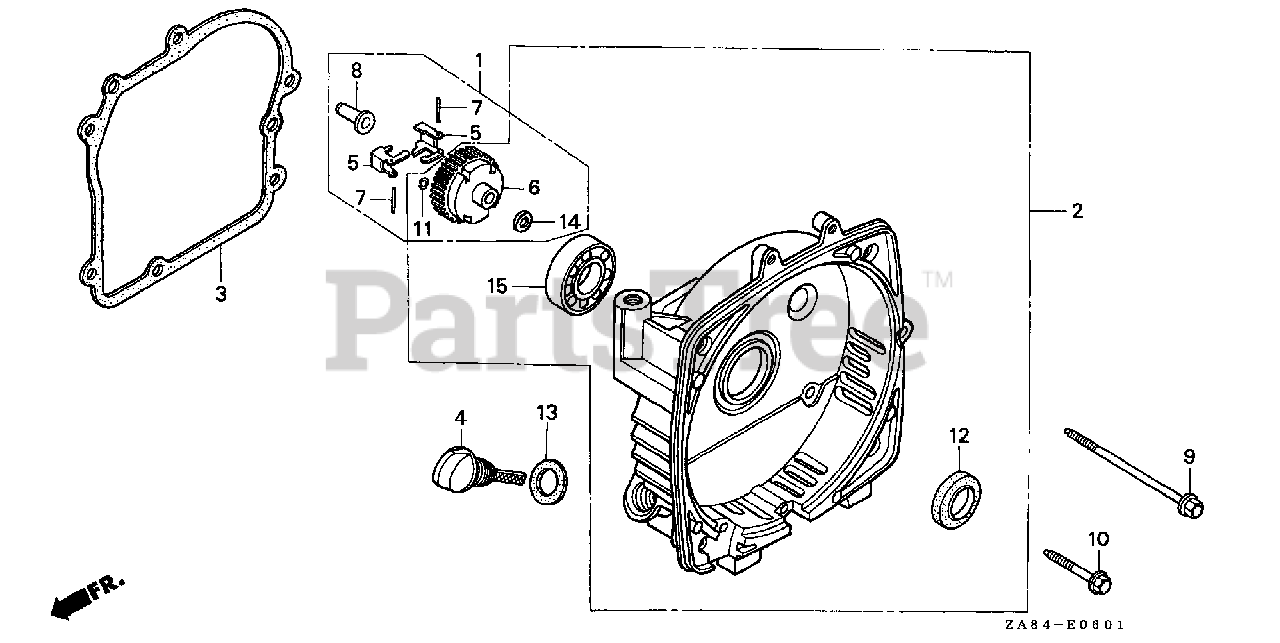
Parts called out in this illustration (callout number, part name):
1	GOVERNOR KIT (STD)
2	COVER ASSY., CRANKCASE
3	GASKET, CASE COVER
4	CAP, OIL FILLER
5	WEIGHT, GOVERNOR
6	HOLDER, GOVERNOR WEIGHT
7	PIN, GOVERNOR WEIGHT
8	SLIDER, GOVERNOR
9	BOLT, FLANGE (6X65)
10	BOLT, FLANGE (6X28)
11	CLIP, GOVERNOR HOLDER
12	OIL SEAL (20X34X6)
13	O-RING (16MM)
14	WASHER, PLAIN (6MM)
15	BEARING, RADIAL BALL (6004)
